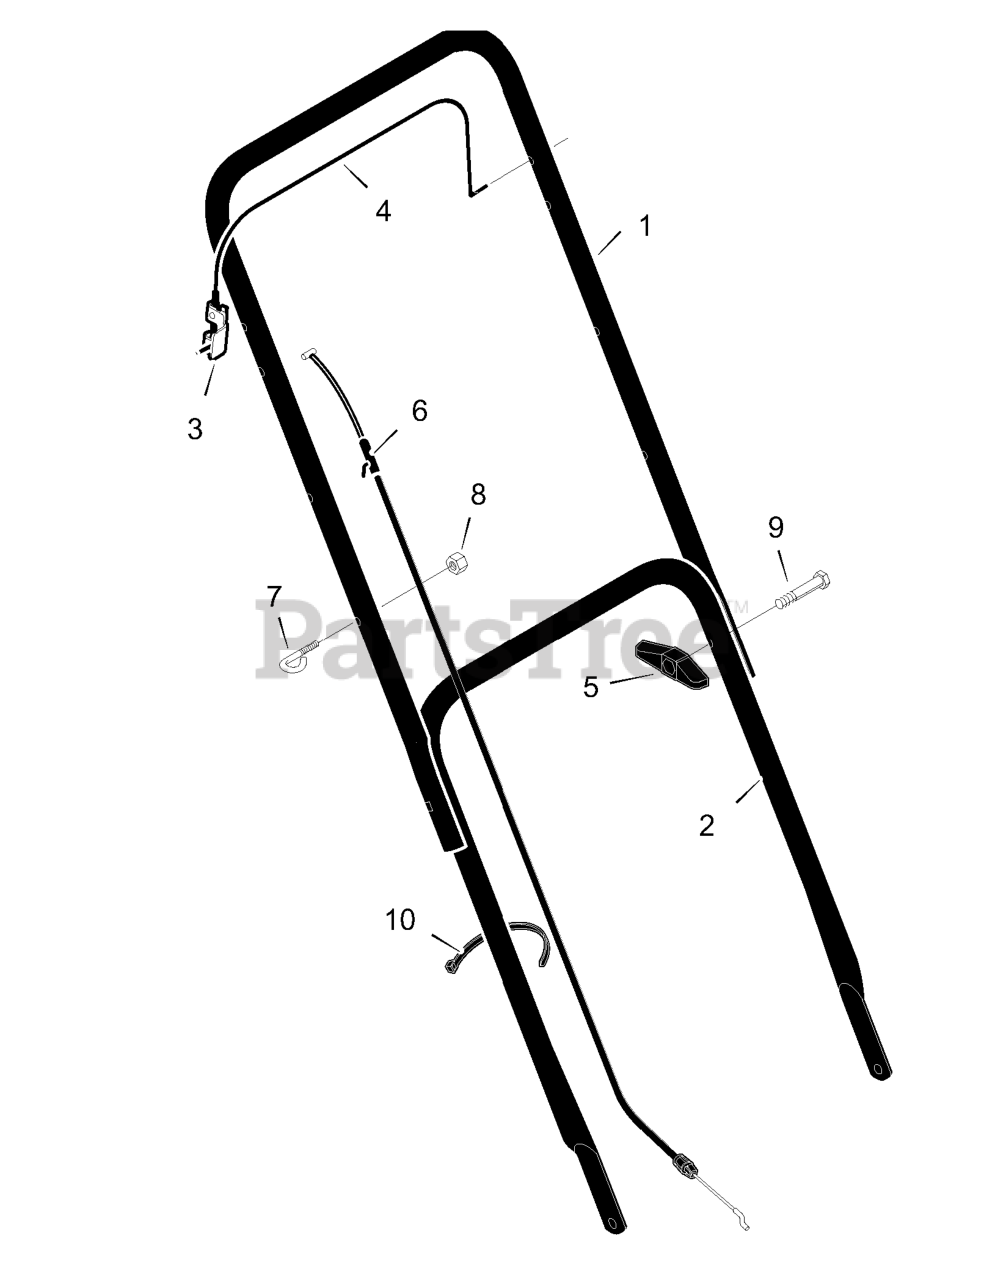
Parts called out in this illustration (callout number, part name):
1	Handle, Upper (Black)
2	Handle, Lower (Black)
3	Bracket, Stop Lever
4	Lever, Stop
5	Knob, Plastic
6	Engine Stop Cable
7	Guide, Rope
8	Locknut
10	Fastener, Cable
